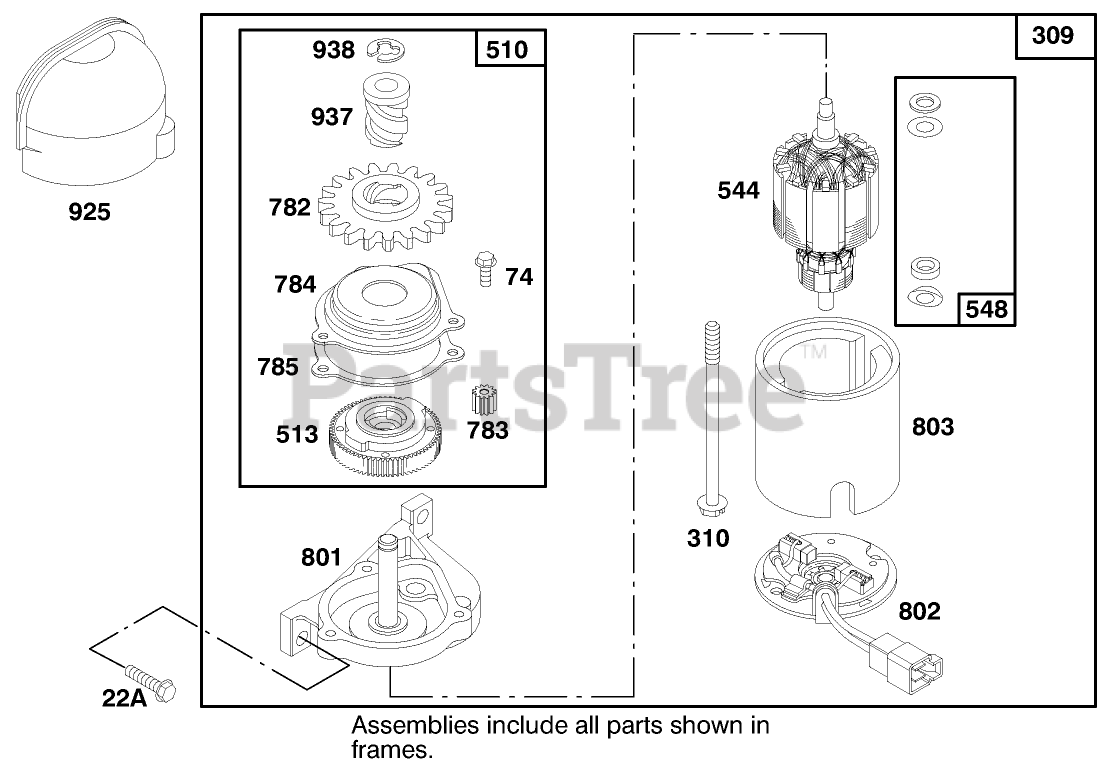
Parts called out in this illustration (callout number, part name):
22A	SCREW - CARBUERTOR MTG
510	DRIVE SET
513	CLUTCH - STARTER
548	WASHER ASSEMBLY
782	GEAR - STARTER
925	COVER - STARTER
938	RETAINER - LOCK
